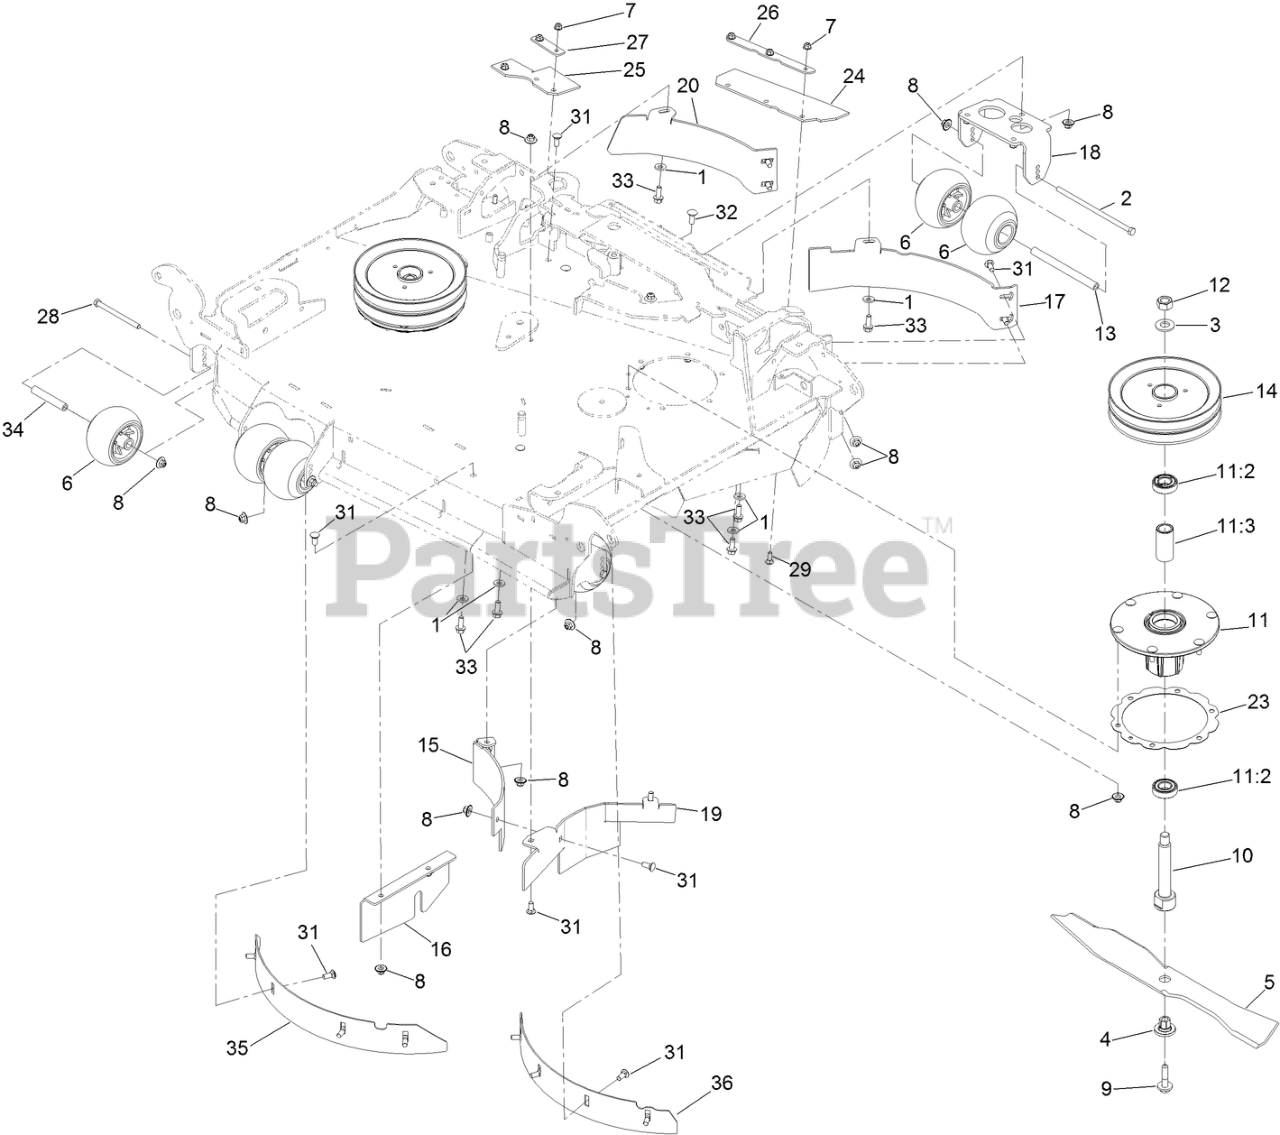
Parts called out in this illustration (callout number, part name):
1	WASHER-BELLEVILLE
2	SCREW-HH
3	WASHER
4	BUSHING-HEX
5	BLADE-24.50 MULCH
6	ROLLER-SCALP, ANTI
7	NUT-HF, NI
8	NUT-FLANGE, NI
9	SCREW-SEMS
10	SHAFT-SPINDLE
11	SPINDLE ASM
11:2	BEARING-BALL
11:3	SPACER-BEARING
12	NUT-HEX
13	SPACER-WHEEL
14	SHEAVE-DOUBLE BLADE DRIVE
15	BAFFLE-CENTER, REAR (RH)
16	PLATE-BLOCK, FRONT
17	BAFFLE-BLOCK, LH CTR
18	BRACKET-ANTISCALP, REAR
19	BAFFLE-CENTER
20	BAFFLE-BLOCK, RH CTR
23	RING-SPACER, HOUSING
24	FLAP-DISCHARGE
25	FLAP-DISCHARGE
26	SUPPORT-FLAP
27	SUPPORT-FLAP, RH
28	SCREW-HH
29	SCREW-CARR
31	BOLT-CARR
32	BOLT-CARR
33	SCREW-HHF
34	SPACER-WHEEL SHORT
35	BAFFLE-DEPTH, LH
36	BAFFLE-DEPTH, RH
